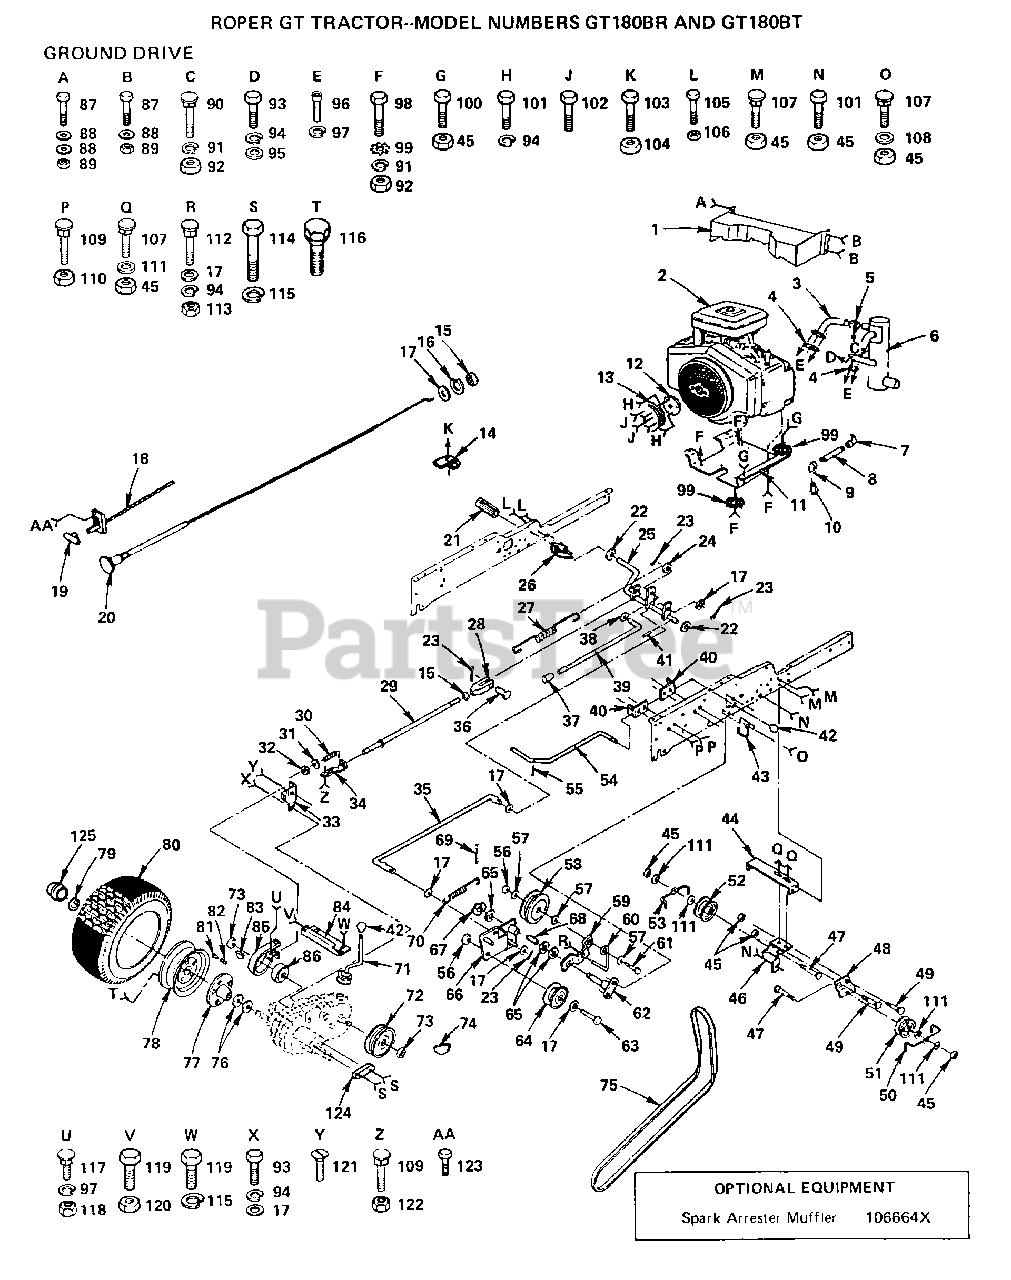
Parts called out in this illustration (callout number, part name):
1	BAFFLE ASSY-ENGINE
3	EXHAUST TUBE T
5	CLAMP-TUBE GTV
11	"ENGINE GT, BASE"
12	ADAPTER T
13	PULLEY GTV
14	ACT-SWITCH T
16	LOCKWASHER
17	WASHER
18	THRTL CONTROL T
21	PEDAL COVER T
24	WASHER M
25	SHAFT ASSY GT
26	BRKT SWITCH GT
27	EXT SPRING GT
28	YOKE GTV
29	BRAKE ROD T
30	SPRING T
31	WASHER
33	BRAKE BRKT ASSY T
34	GUIDE ROD T
35	ROD CLUTCH GTV
36	CLEVIS PIN T
37	PLUNGER CAP T
38	WASHER
40	ROD BRACKET GT
41	ROLL PIN STD
43	BELT RETAINER GT
44	BRACKET-DRIVE GT
46	BRKT-V-PULLEY GT
47	BOLT
49	BOLT
51	IDLER-FLAT T
52	PULLEY V IDLR GTV
53	BELT GUARD GT
54	ROD SHIFT GTV
56	LOCKNUT
57	WASHER
60	BELT RETAINER GT
62	BRACKET ASSY GTV
65	WASHER T
66	CLUTCH BRACKET GT
67	KLIP RING
68	"GTV, BEARING"
69	COTTER PIN
70	SPRING GTV
71	GEAR SHFT LVR T
72	PULLEY GTV
73	NUT STD
75	BELT-V.93.07
76	WASHER T
79	KLIP RING
81	VALVE CAP
82	VALVE STEM LT
86	BRAKE DRUM T
88	WASHER
89	LOCKNUT
91	LOCKWASHER
92	NUT.HEX.5/16-18
94	LOCKWASHER
95	WASHER
97	LOCKWASHER
98	BOLT
99	LOCKWASHER.5/16.E
101	BOLT
103	SCREW
105	BOLT LT
107	BOLT D
108	WASHER
111	WASHER GT
113	NUT
115	LOCKWASHER
117	BOLT T
119	BOLT
120	NUT GTV
121	SCREW
123	SCREW
125	CAP-HUB GT
